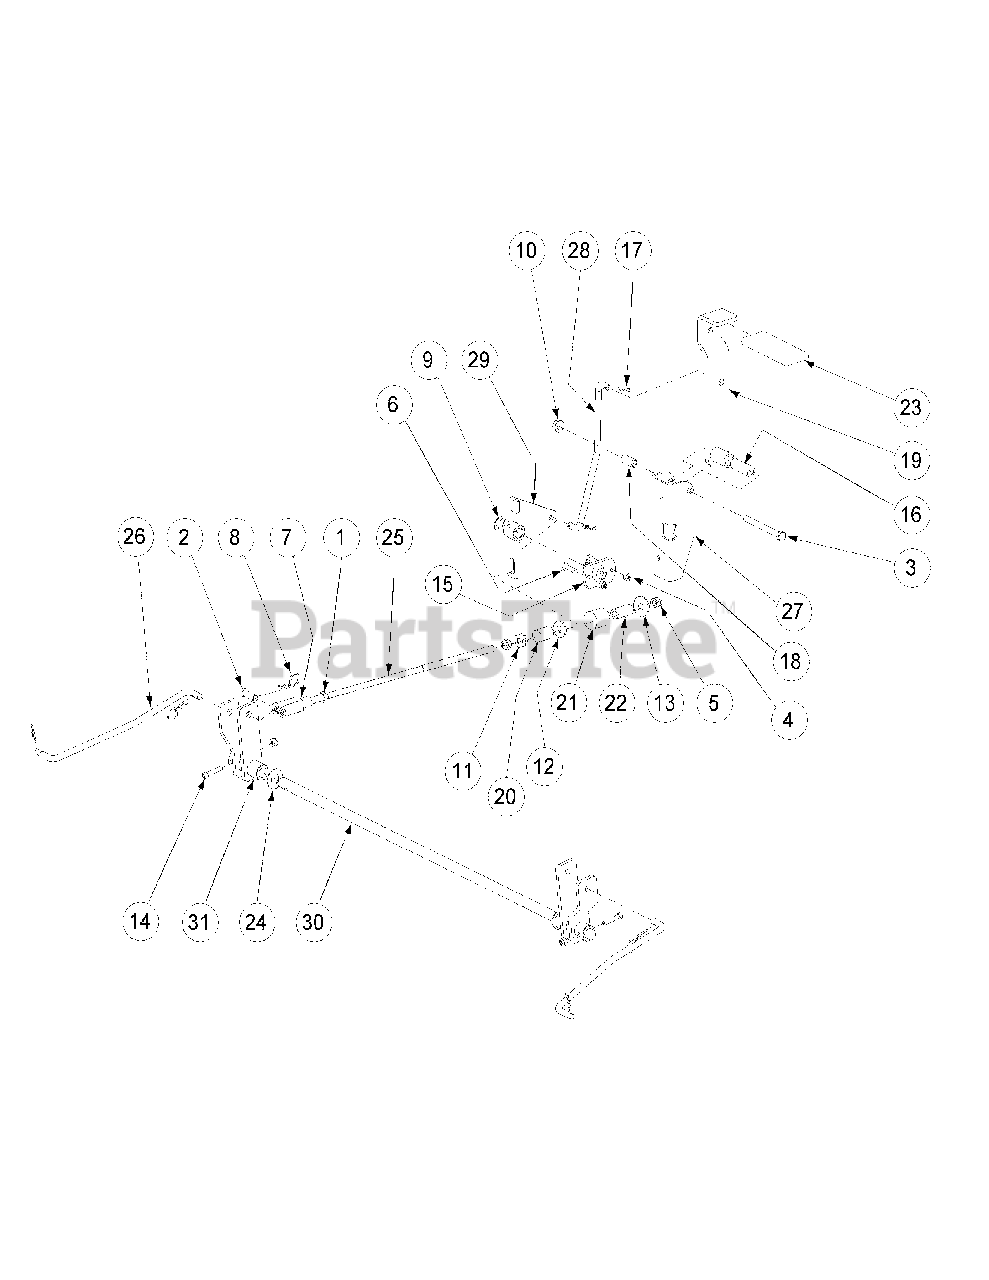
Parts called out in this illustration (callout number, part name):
1	Hex Nut, 3/8-16
2	Clevis Pin, 3/8 x 1-1/8
3	Hex Cap Screw, 3/8-16 x 3-1/2
4	Lock Nut w/Nylon Insert
5	Nylock Nut, 3/8-16
6	Hex Cap Screw, 1/4-20 x 1.00
7	Yoke, 3/8-16
8	Hair Pin, 3/8" - 1/2"
9	E-Ring, 5/8" #5113-62
10	Flange Lock Hex Nut, 3/8-16
11	Shoulder Nut
12	Flat Washer, .406 ID x 1.0 OD x .105
13	Flat Washer, .411 x 1.25 x .100
14	Socket Screw, 1/4-20 x 1.25
15	Bellecrank Pivot, Weldment
16	Spacer, .39ID x .63OD x 1.75LG
17	Cotter Pin, .072 x 1.12 Lg
18	Spacer, .375 ID x .50 x 1.02 Lg
19	Brake Handle
20	Neutral Brake Spring
21	Force Brake Spring
22	Center Brake Hose
23	Parking Brake Grip
24	Flat Washer, 5/8
25	Connector Rod, 3/8 OD x 16.88 Lg
26	Rear Brake Linkage Rod
27	Parking Brake Mounting Bracket
28	Park Brake Handle Rod
29	Park Brake Bellcrank
30	Park Brake Shaft
31	Rear Brake Arm Assembly
